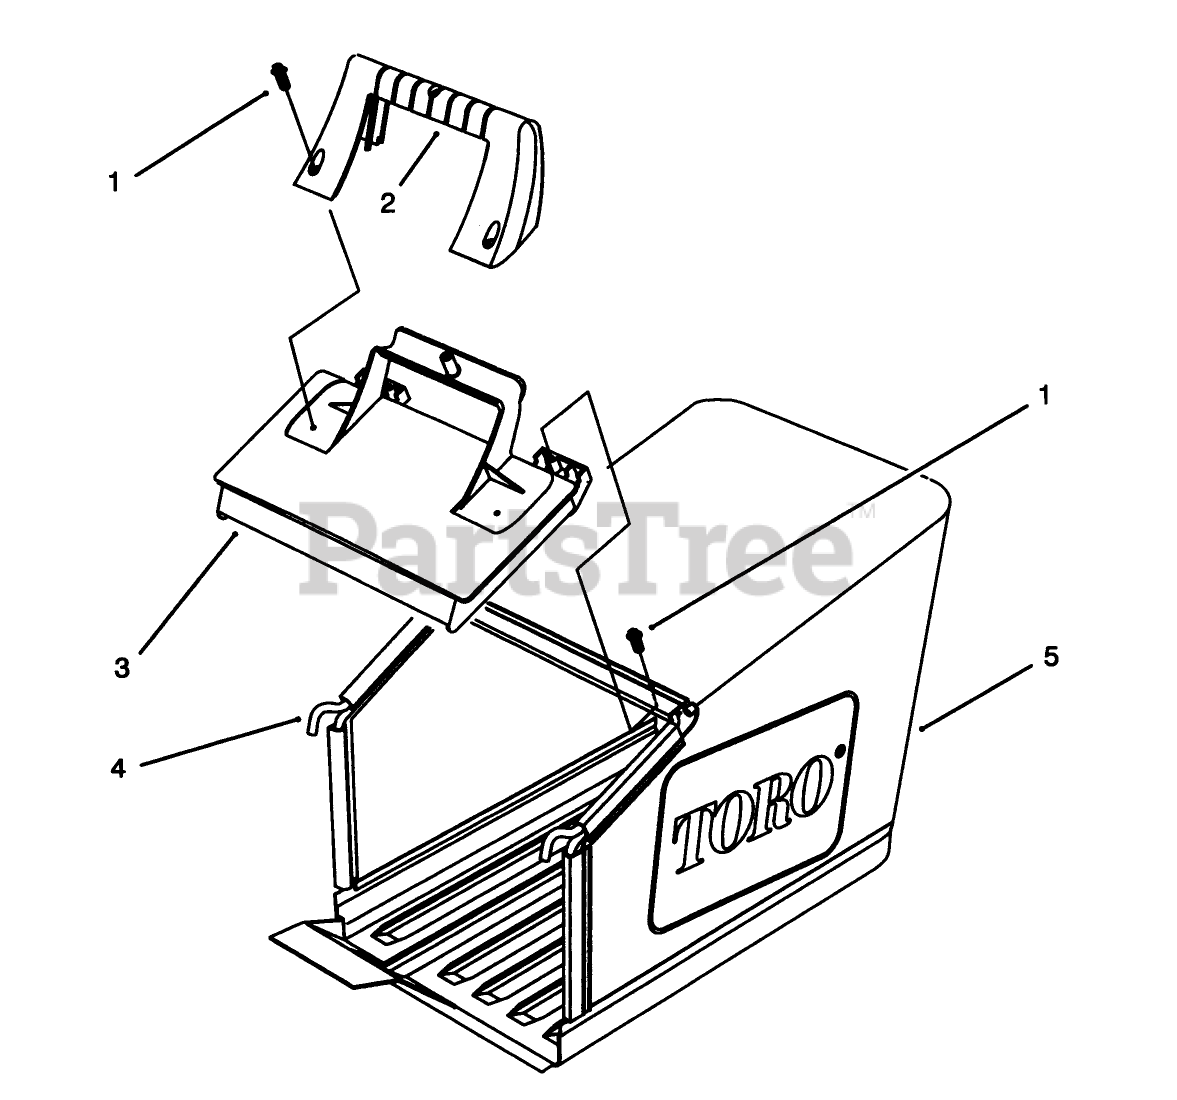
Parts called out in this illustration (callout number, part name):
1	SCREW-PPH
2	HANDLE-DOOR
3	DOOR-BAG
5	GRASS BAG 48CM W/PAN
